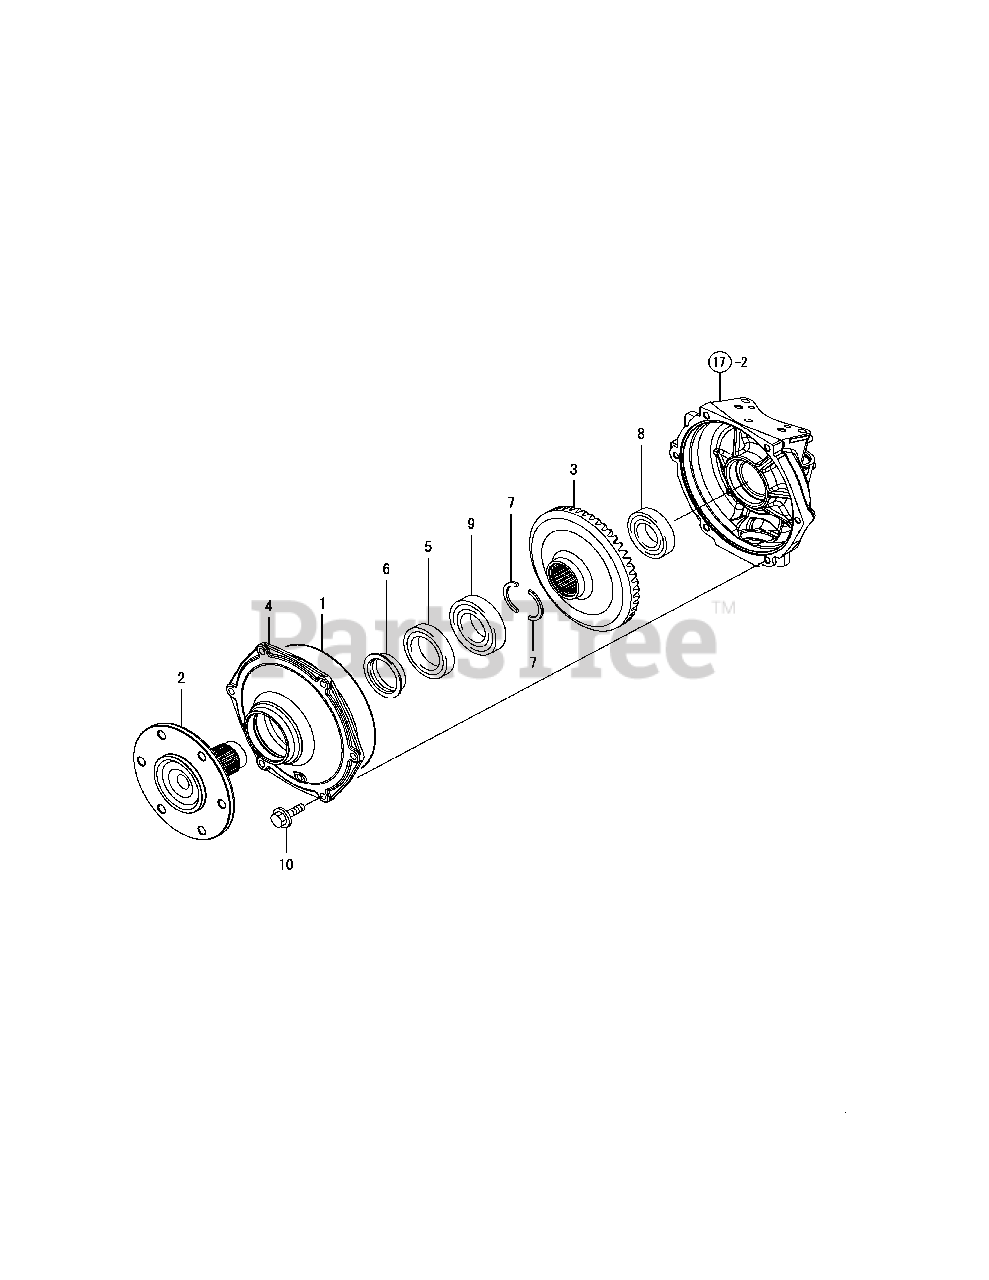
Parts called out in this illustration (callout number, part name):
1	O-RING 190X2.7
2	SPINDLE, FRONT
3	GEAR, FRONT FINAL
4	COVER, GEAR BOX
5	SEAL TC6Y 57 75 12
7	RING, HALF TIMBER
10	BOLT M10X 25 PLATED
